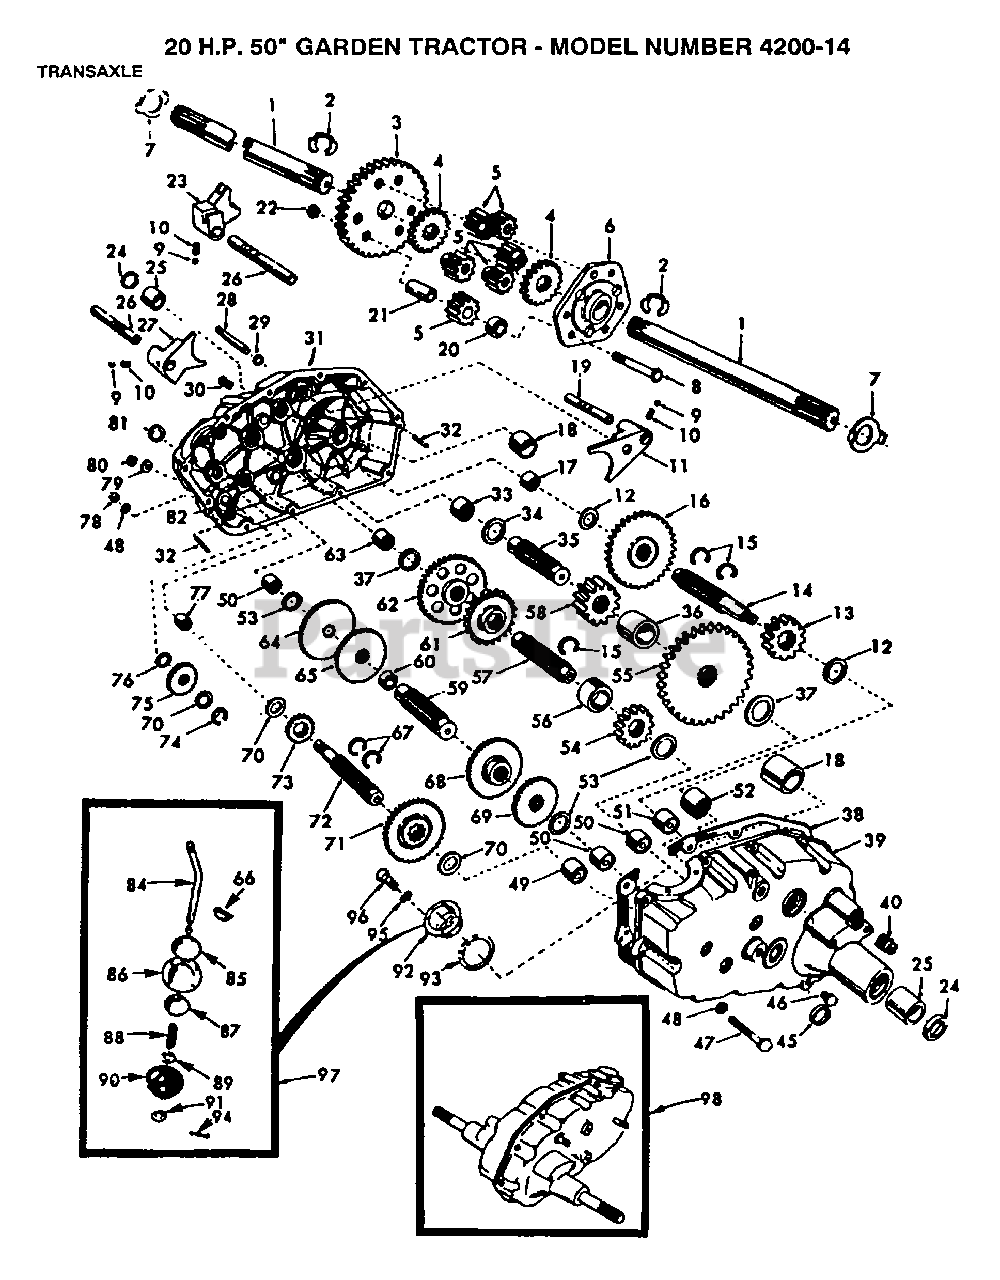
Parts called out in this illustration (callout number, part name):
1	SHAFT.AXLE.T
2	KLIP RING
3	FINAL GEAR T
4	DIFF GEAR T
5	DIFF PINION T
6	DIFF CARRIER T
8	BOLT
11	SHIFT FORK T
12	WASHER .T
13	RED PINION T
14	GEAR SHAFT T
15	SNAP RING T
16	GEAR T
17	"T, BEARING"
18	BEARING
19	SHAFT
20	SPACER T
21	PINION RS
22	GRIPCO NUT
23	SHIFT FORK T
24	OIL SEAL STD
25	BRNG. T
27	FORK T
28	SHIFT SHAFT
29	SEAL T
30	VALVE M
31	GEARCASE RH
32	PIN T
33	NEEDLE BRNG T
34	RACE T
35	GEAR SHAFT T
37	RACE T
38	GASKET
39	GEARCASE LH
40	PLUG PIPE
45	SEAL T
47	HEX BOLT
49	"TI, BEARING"
50	NEEDLE BRNG T
51	NEEDLE BRNG T
52	"STD, BEARING"
53	BRNG RACE
54	RED PINION T
55	RED GEAR T
56	PINION SPACER T
57	GEAR SHAFT T
58	FINAL PINION T
59	GEAR SHAFT T
60	SPACER T
61	RED PINION T
62	RED GEAR T
63	RACE T
64	LOW SPEED GEA T
65	REVERSE GEAR T
66	No Desciption for Part
67	RING STD
68	INTERMED GEAR T
70	"T, BEARING"
71	CLUSTER GEAR T
72	INPUT SHAFT T
73	LO SPEED PINION T
75	IDLER GEAR T
76	WASHER T
77	BRNG T
78	NUT.HEX.5/16-18
79	WASHER T
80	NUT
81	SEAL STD
84	GEAR SHIFT LVR T
85	CAP T
86	COVER AND PIN T
87	SHIFT LEVER GUIDE BALL
88	SPRING TI
89	WASHER
90	SEAL T
91	WASHER
92	GEAR SHIFT GA T
93	GASKET T
94	COTTER PIN
95	LOCKWASHER
96	BOLT
